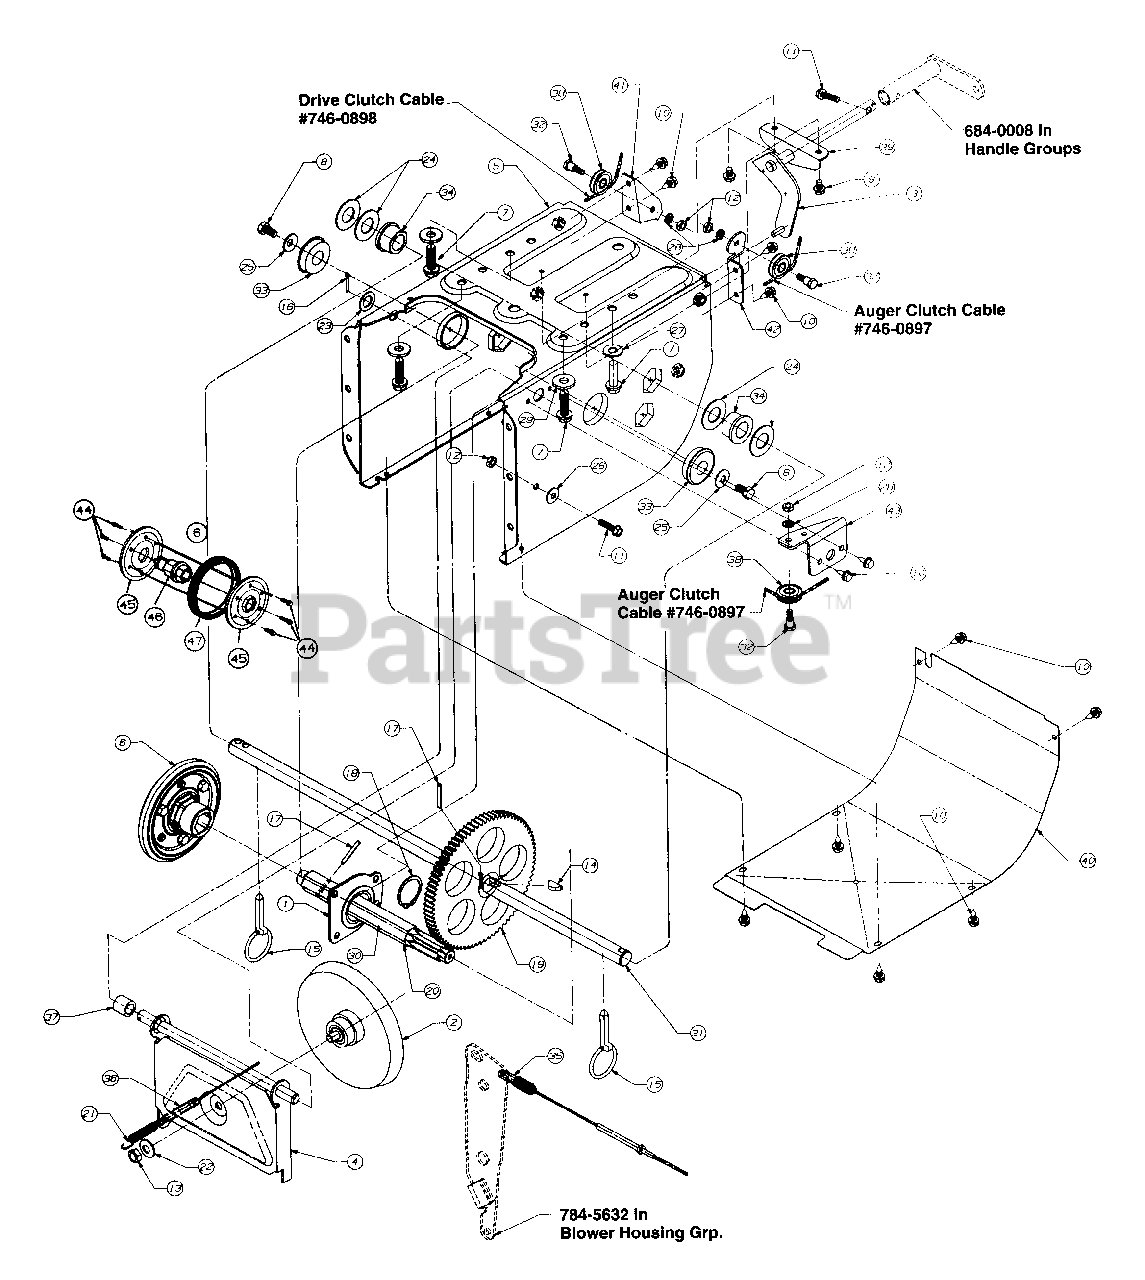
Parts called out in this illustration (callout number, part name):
1	Bearing Ass'y.
2	Ass'y., Friction Wheel Disc
3	Rod Shift, Wheel Drive
4	Brkt. Ass'y. Friction Wheel
7	Hex Self-Tap Screw
8	Hex, Screw
9	Scr., Hex Wash. Hd., TT 1/4-20 x .3
10	Hex Self-Tap Scr.
11	Screw, Hex
12	Nut, Hex
13	Nut, Hex
14	Key
15	Pin, Klick
16	Pin, Cotter
17	Pin, Roll
18	Ring, Retainer
19	Gear
20	Shaft, Hex
21	Extension Spring
22	Washer, Bell
23	Flat Washer
24	Washer, Flat
25	Washer, Bell
26	Washer, Bell
27	Flat Washer
28	Washer, Lock
29	Washer, Flat
30	Lubricant
31	Axle
32	Screw, Shoulder
33	Bearing, Ball
34	Flange Bearing
35	Cable, Auger
36	Cable, Clutch
37	Spacer
38	Roller, Cable
44	Hex Wash Hd. TT-Tap Scr. 1/4-20 x .5" Lg.
45	Friction Plate
46	Friction Wheel Hub
47	Friction Wheel Rubber
